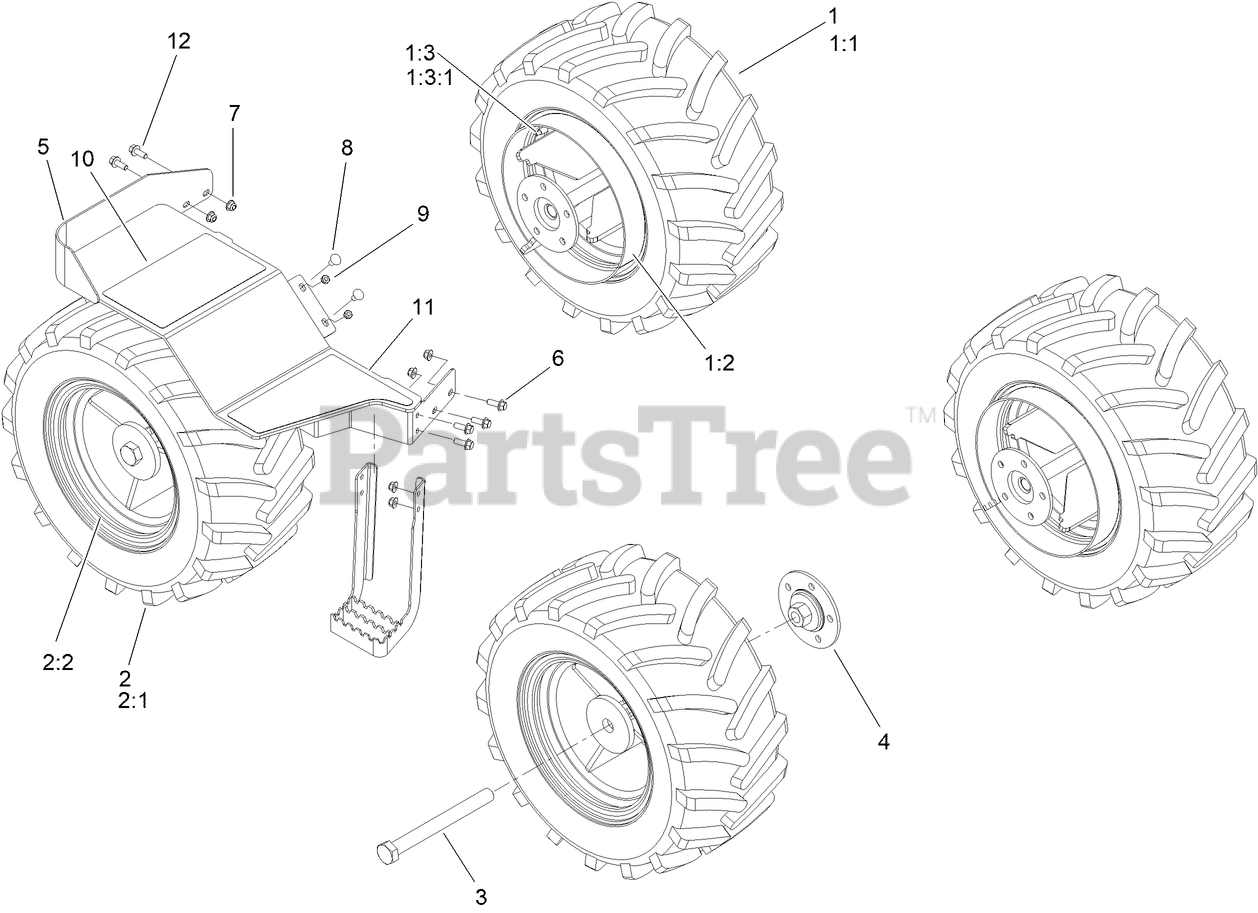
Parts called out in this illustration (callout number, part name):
1	LH DUAL 23X10.50-12 WHEEL ASM
1:1	TIRE (23 X 10.50-12, B6TL)
1:2	WHEEL-DUAL
1:3	VALVE STEM (.453", SNAP-IN)
1:3:1	VALVE CAP (.305"-32)
2	RH DUAL 23X10.5-12 WHEEL ASM
2:1	TIRE (23 X 10.50-12, B6TL)
2:2	WHEEL-DUAL
3	SCREW-HH
4	PLATE - RETAINER DUAL WHEEL
5	PLATFORM-EXTENSION DUAL 23"
6	SCREW-HHF
7	NUT-HF, NI
8	SCREW-CARR
9	NUT-HEX
10	NON-SKID
11	NON-SKID
12	SCREW-HHF
